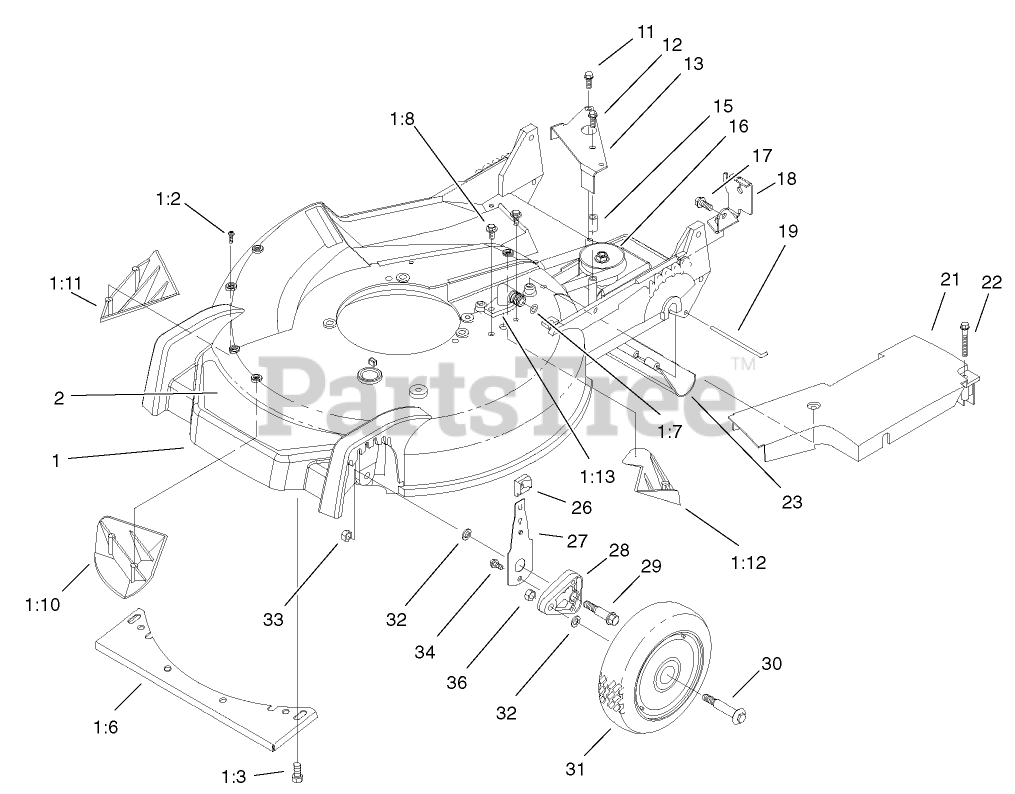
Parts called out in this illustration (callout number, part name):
1:2	SCREW-PPH
1:3	SCREW-HWHTF
1:7	O-RING
1:8	SCREW-HWH
1:10	KICKER-FRONT
1:11	KICKER-RH
1:12	KICKER-REAR
2	DECAL-DECK
11	SCREW-HWHTF
12	SCREW-HWHTF
13	BRACKET-TRANSMISSION ACTUATOR
15	BUSHING-PLATE, ACTUATOR
17	SCREW-HWHTF
18	BRACKET-CABLE, TRACTION
19	ROD-SHIELD
22	SCREW-HWH
26	KNOB-ARM
27	FRONT SPRING ARM ASM
28	ARM-PIVOT, FRONT
29	BOLT-SHOULDER
30	BOLT-SHOULDER
31	WHEEL ASM
32	WASHER
33	NUT-LOCK
34	SCREW-HWH
36	LOCKNUT
